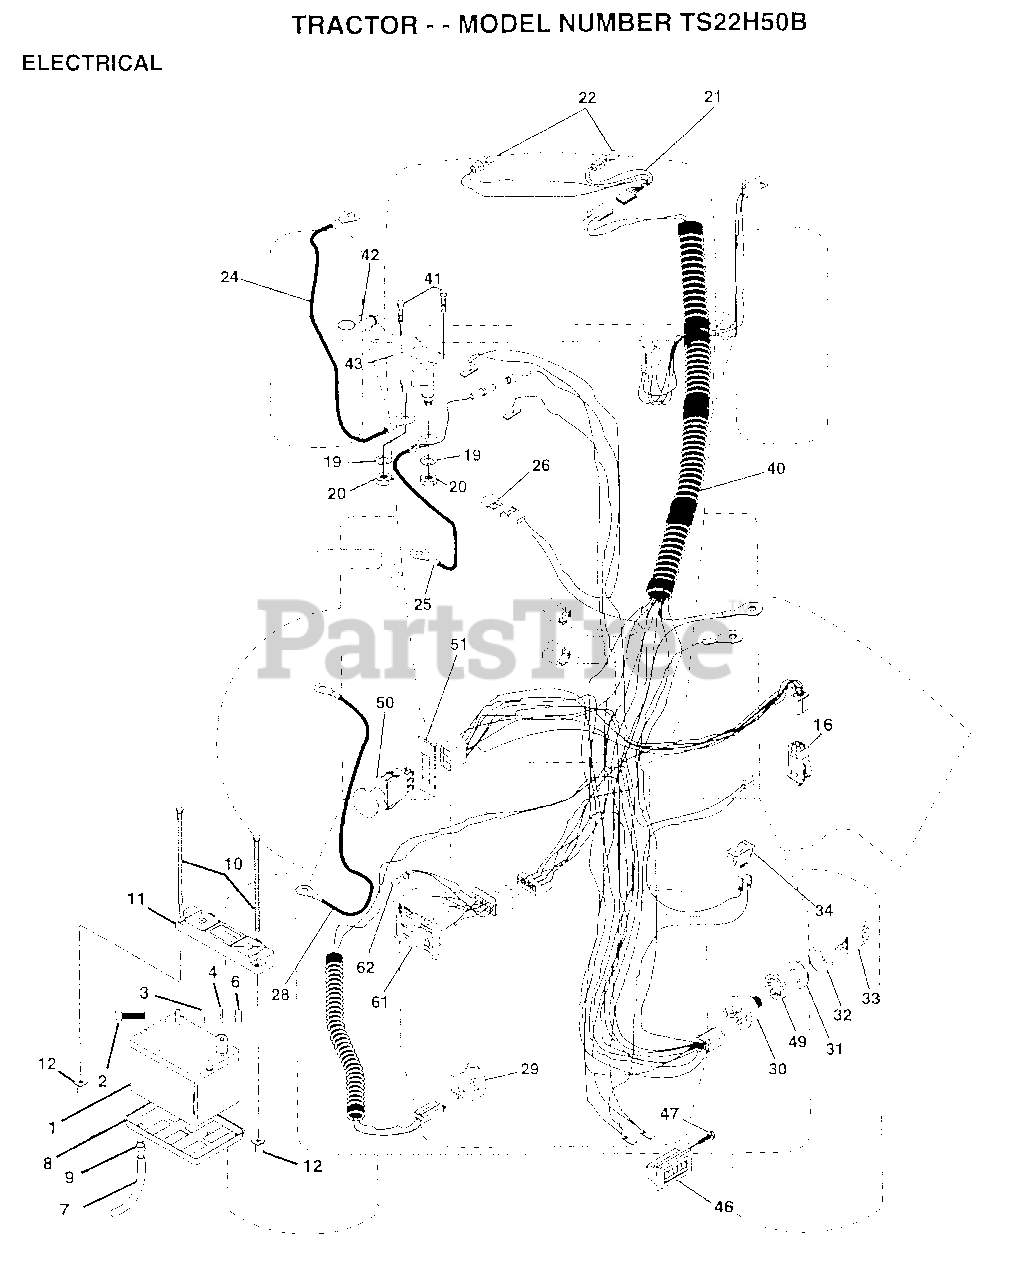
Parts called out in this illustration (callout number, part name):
2	BOLT LT
3	LOCKWASHER
4	WASHER
7	"DRAIN TU T, BATT"
8	"TRAY T, BATTERY"
9	HOSE CLAMP T
20	NUT
21	"HARNESS,LIGHT SOC"
22	HEADLAMP BULB
24	CABLE.BATY.22.RED
25	CABLE.BATRY.4GA.
26	FUSE HYT
28	CABLE.BATRY.4GA.
29	SWITCH SEAT
32	COVER KEY SWITCH
33	KEY MLD GEN DELTA
34	SWITCH LT
39	SWITCH INTERLOCKT
40	HARNESS.IGNITION
41	SCREW
46	HOUR METER T
47	SCREW
49	WASHER PINNED
51	RING RETAIN PTO
53	SCREW
54	"NUT,KEPS"
61	LIGHT.PKG.ASM.
62	BULB LIGHT T
